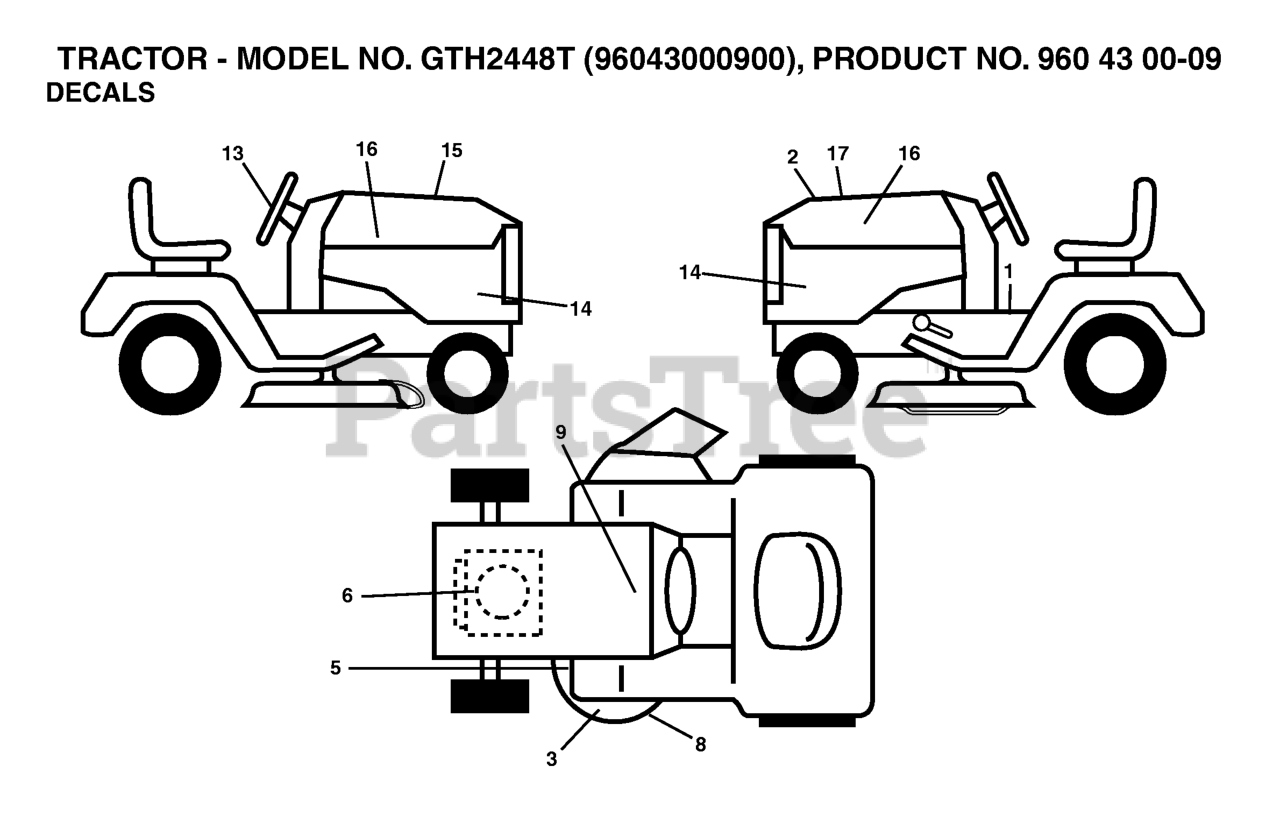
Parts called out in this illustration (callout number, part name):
2	DECAL.HOOD.TOP.INSERT.
3	DECAL.WARN.KEEP.HAND.AWAY
5	DECAL CLUTCH/BRAKE
8	DECAL.MOWER.SCH.48/54
9	DECAL BTRY SYMBOLS
13	DECAL.STEERING.HUSQ.BLUE
15	DECAL HOOD CUST. RESP.
16	DECAL.HOOD.NAMELOGO.HUSQ
